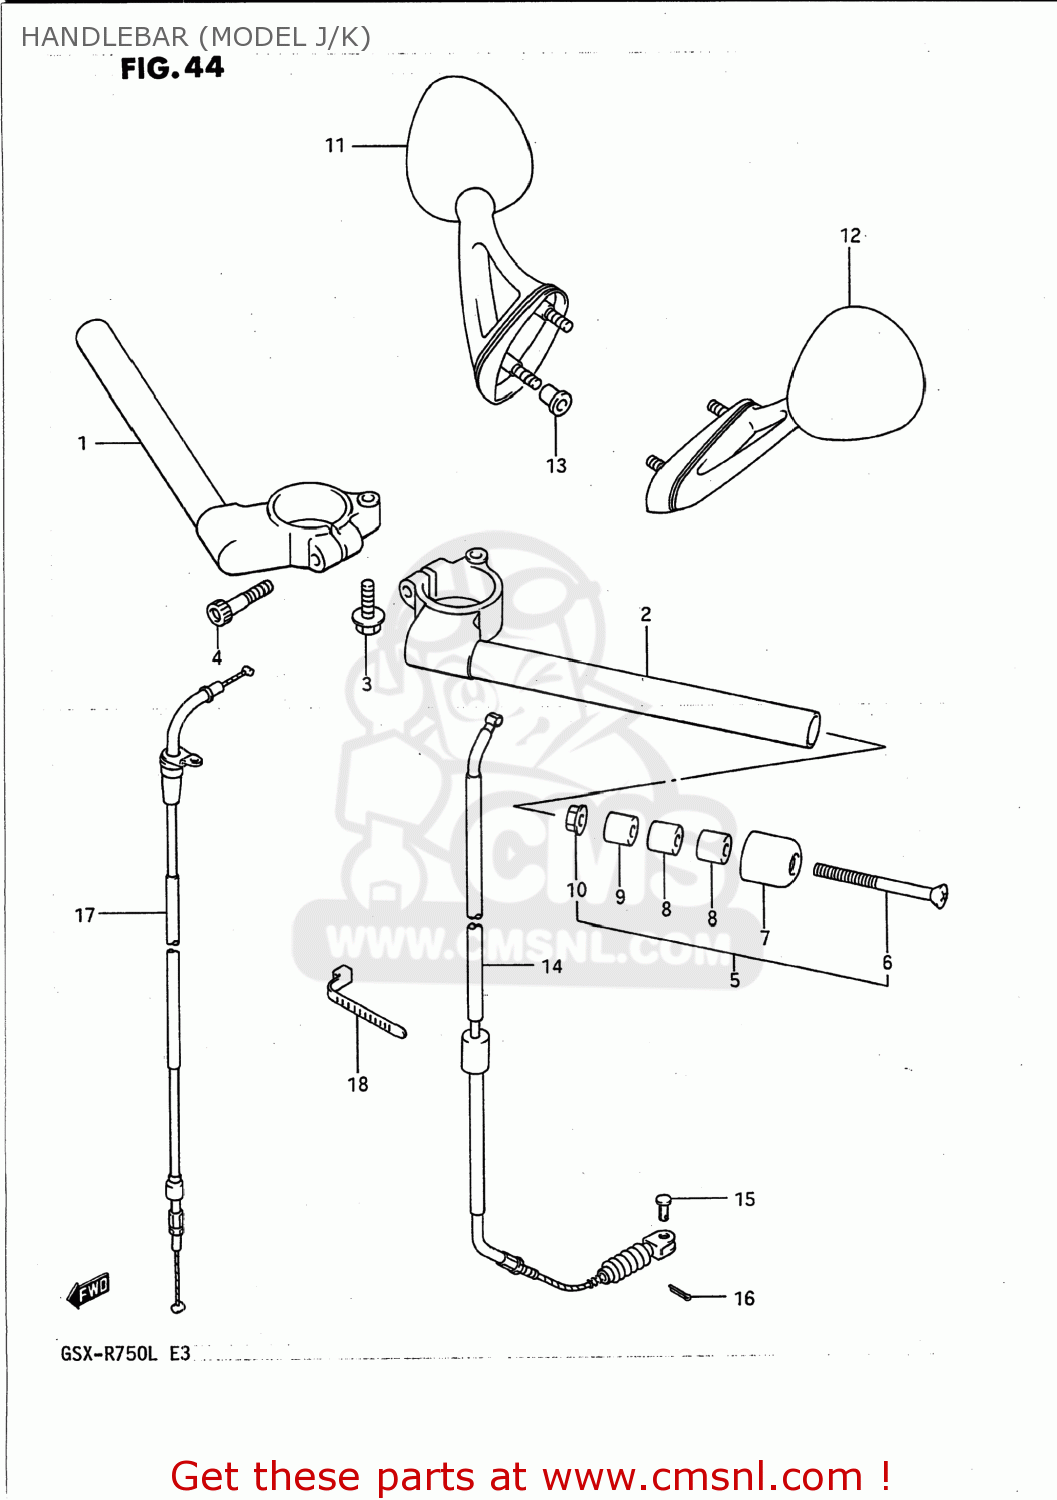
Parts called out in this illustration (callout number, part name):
1	HANDLEBAR,R
2	HANDLEBAR,L
3	BOLT
4	BOLT 8X35
5	BALANCER SET,HANDLEBAR
6	SCREW(6X85)
7	CAP,BALANCER
8	BALANCER,HANDLEBAR INNER
9	EXPANDER,HANDLE BALANCER
10	NUT
11	MIRROR ASSEMBLY,REAR VIEW
12	MIRROR ASSEMBLY,REAR VIEW
13	NUT,RR VIEW MIRROR
14	CABLE ASSY,CLUTCH
15	PIN(L:15)
16	PIN
17	CABLE ASSY,THROTTLE
18	CLAMP(L:165)
